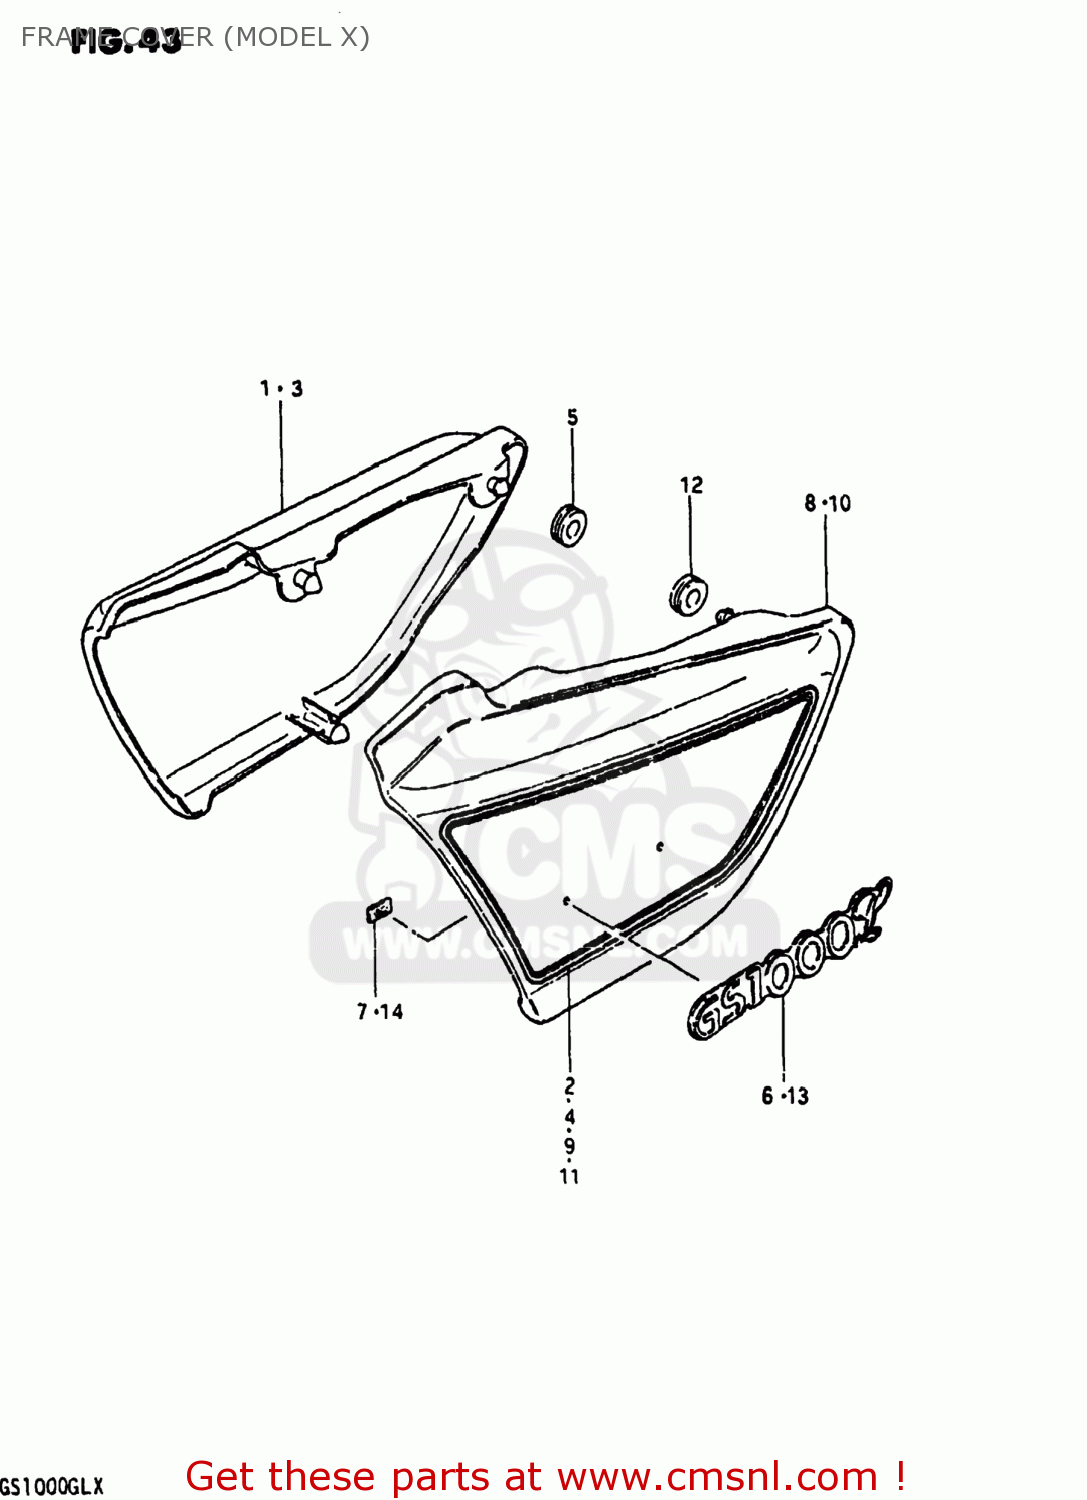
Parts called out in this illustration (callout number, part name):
1	COVER ASSEMBLY,FRAME,RIGHT
2	TAPE,FRAME COVER,RIGHT
3	COVER ASSEMBLY,FRAME,RIGHT
4	TAPE,FRAME COVER,RIGHT
5	CUSHION
6	EMBLEM
7	NUT
8	COVER ASSEMBLY,FRAME,LEFT
9	TAPE,FRAME COVER
10	COVER ASSEMBLY,FRAME,LEFT
11	TAPE,FRAME COVER
12	CUSHION
13	EMBLEM
14	NUT
